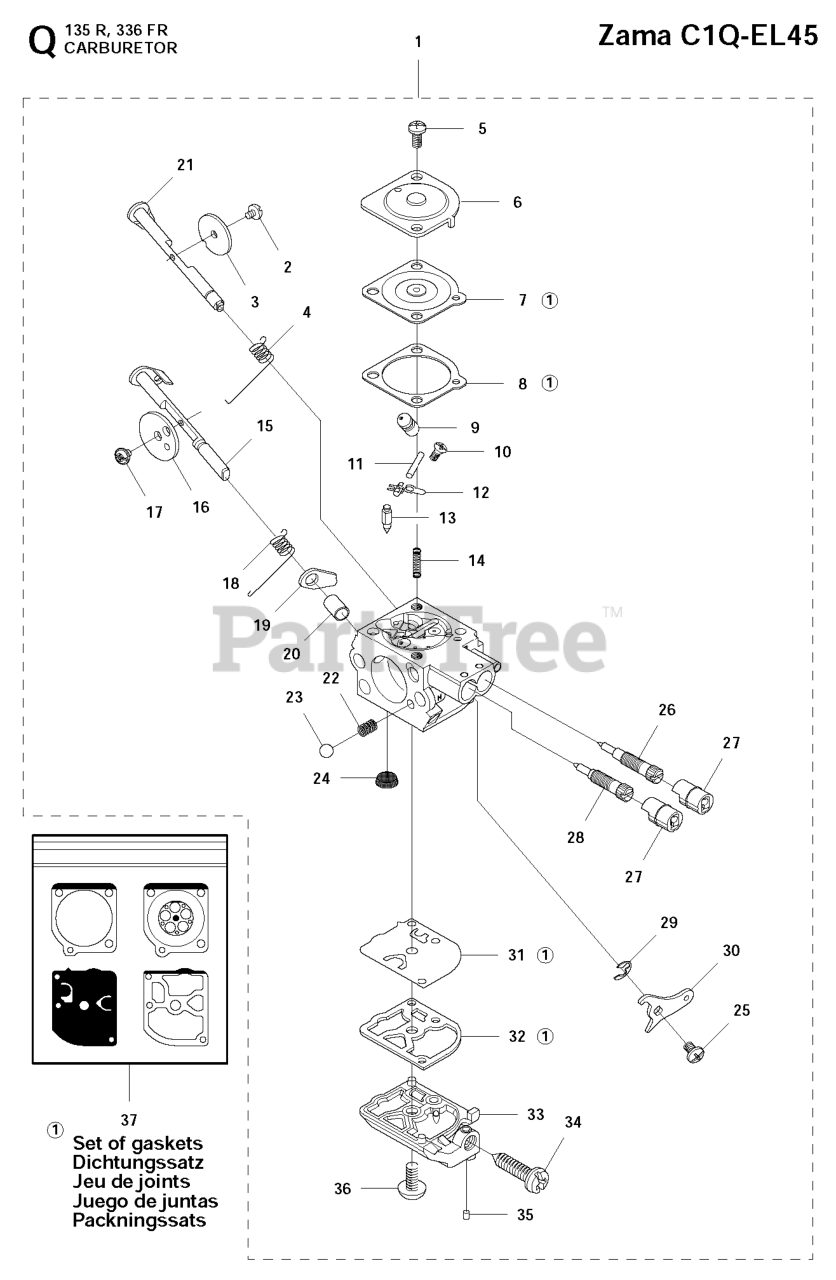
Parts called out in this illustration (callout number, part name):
1	CARBURETOR
4	RETURN SPRING
11	PIN RETAINING SCREW
13	INLET NEEDLE
14	SPRING
15	SHAFT ASSY
21	SHAFT ASSY
24	FUEL INLET SCREEN
26	IDLE SCREW
27	LIMITER CAP KIT
30	THROTTLE LEVER
31	PUMP DIAPHRAGM
37	GASKET KIT (ZAMA GND39)
